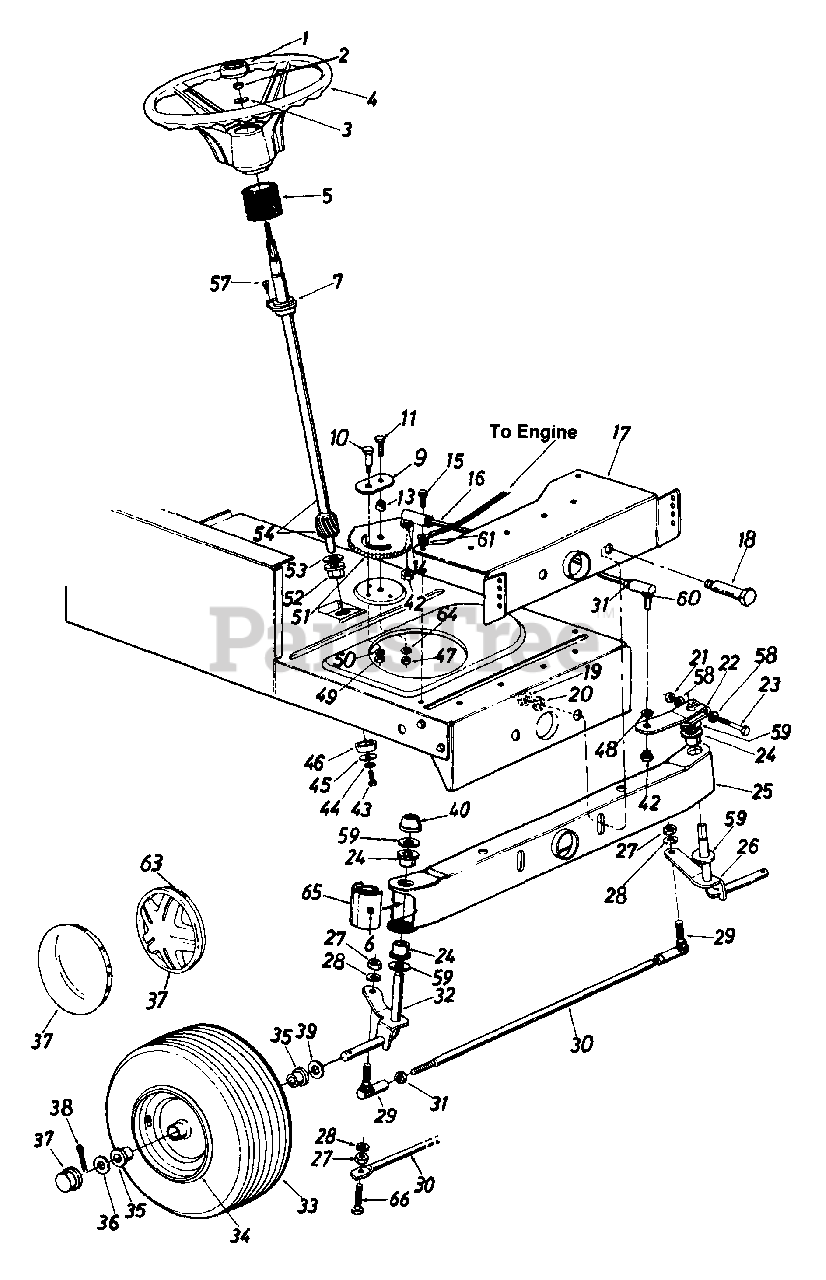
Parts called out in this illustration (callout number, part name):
1	Steering Wheel Cap
2	Hex L-Nut 5/16-24 Thd.
3	Belleville Wash..345" I.D.
4	Steering Wheel (3 Spoke)
5	Steering Bellow - 4.5" (Style 2, 3, 5, 7, 8}
6	Grease Fitting (Optional)
7	Flange Bearing .890 I.D. x 1.36 O.D. (Style 2, 3, 5, 7, 8)
9	Retainer Plate New Part
10	Shoulder Bolt .437" Dia. x.35 Lg. 5/16-18 Thd.
11	Hex Bolt 3/8-24 x 1.0" Lg. (Grade 5)
13	Spacer.380" I.D. x.625" O.D. x .227
14	L-Wash. 3/8" I.D.
15	Hex Wash. Hd. Self-Tap Scr.
16	Steering Drag Link
17	Front Pivot Brkt.
18	Shoulder 8olt .498" Dia. x 2.04 Lg. 3/8-16 Thd.
19	Hex Nut 3 8-16 Thd.
20	L-Wash. 3/8" I.D.
21	Hex Cent. L-Nut 5/16-24 Thd.
22	Steering Arm Front Axle
23	Hex Bolt 5/16-24 x 2.00" Lg. (Grade 5)
24	Hex Flg. Brg..632 I.D. x .817 O.D. use with 683-0002
24	Bearing Flange .632 I.D. x .937.O.D. use with 683-0128B
25	Kit, Pivot Bar Assy with Bearing Flanges
26	Front Axle Ass'y.- L.H. 15" x 6" w/Plastic Bearing
27	Hex Nut 3/8-24 Thd.
28	L-Wash. 3/8" I.D.
29	Ball Joint 3/8-24 Thd.
30	Tie Rod (Adjustable)
31	Hex Jam Nut 3/8-24 Thd.
32	Front Axle Ass'y.- R.H. 15" x 6" w/Plastic Bearing
36	Fl-Wash .635 I.D. x 1.59" O.D.
37	Front Wheel Hub Cap
38	Cotter Pin 1/8" Dia. x 1.25"
39	Fl-Wash .640" I.D. x 1.24" O.D.
40	Push Cap 5/8" Dia. Rod
42	Hex Jam Nut 3/8-24 Thd.
43	Hex L-Bolt 5/16-18 x .62"
44	L-Wash. 5/16" I.D.
45	Fl-Wash 33" I.D. x 1.25" O.D.
46	Spacer (Plastic)
47	Hex Cent L-Nut 3/8-24 Thd.
48	L-Wash. 3/8" I.D.
49	Hex Cent. L-Nut 5/16-18 Thd.
50	L-Wash 5/16" I.D.
51	Steering Gear Segment
52	Hex Flg Brg .634 I.D.
53	Fl-Wash (Hardened)
54	Steering Shaft
57	Oval Hd Cr.- Sunk Scr #10 x 5/8" Lg.(Style 2, 3, 5, 7, 8)
58	Wave-Wash .32" I.D. x .62" O.D.
59	Fl-Wash (Hardened)
60	Drag Link Ball Joint 3/8-24 Thd.
61	Ext L-Wash. 5/16" I.D.
63	Spring Clip (Used a/Spoked Hub Cap)
64	Bell-Wash 39" I.D. x 1.38" O.D.
65	Pivot Bar End Cap (Optional)
66	Hex Bolt 3/8-24 x 1.5" Lg. (Gr. 5)
